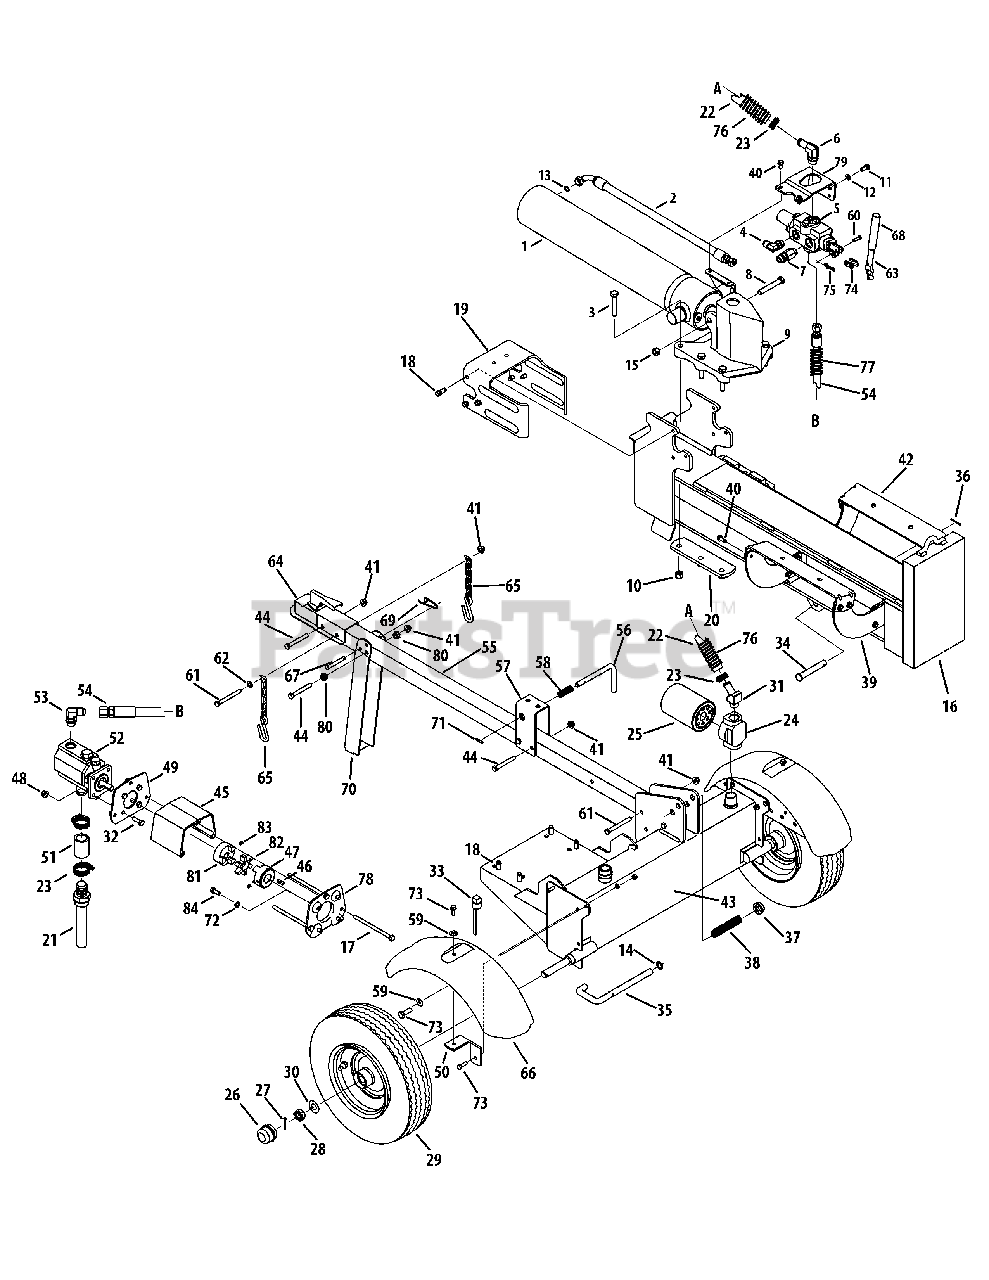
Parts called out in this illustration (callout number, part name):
1	Hydraulic Cylinder
2	Hydraulic Tube
3	Hex Cap Screw, 1/2-20 x 2.75
4	90 Degree Solid Adapter
5	Control Valve
6	Return Elbow
7	Nipple Pipe, 1/2-14
8	Hex Cap Screw, 1/2-13 x 3.25
9	Wedge Assembly
10	Hex Lock Nut, 1/2-20
11	Hex Cap Screw, 3/8-16 x .75
12	Lock Washer, 3/8
13	O-Ring, .489 ID x .070 Dia.
14	Flat Washer, .635 x.93 x.06
15	Hex Lock Nut, 1/2-13
16	Beam Assembly
17	Hex Screw, 5/16-18 x 4.00
18	Self Tapping Screw, 3/8-16 x 1.0
19	Dislodger Bracket
21	Inlet Filter
22	Return Hose, 3/4 x 44
23	Hose Clamp, 5/8
24	Filter Housing
25	Oil Filter
27	Cotter Pin
28	Slotted Nut, 3/4-16
29	Complete Wheel Assembly
29	Dust Seal
29	Roller Bearing
30	Flat Washer, .760 x.500
31	Hydraulic Fitting, 1 1/16 Orb x .75
32	Hex Screw, 5/16-18 x 1.00
33	Vented Dipstick
34	Clevis Pin
36	Cotter Pin
38	Compression Spring
39	Log Tray Bracket
40	Hex Washer Screw, 5/16-18 x .750
41	Flange Lock Nut, 3/8-16
43	Frame Assembly
44	Hex Bolt, 3/8-16 x 3
45	Coupling Shield
46	Square Key, 3/16" x .75
47	Coupling, .750
48	Flange Lock Nut, 5/16-18
49	Rear Coupling Support Bracket
50	Fender Mounting Bracket
53	45 Degree Elbow Fitting
54	High Pressure Hydraulic Hose
55	Tongue Assembly
56	Latch Rod
58	Compression Spring
59	Flat Washer
60	Clevis Pin
61	Hex Cap Screw, 3/8-16 x 3.50
62	Flat Washer, .375 x.738 x.063
63	Hydraulic Valve Control
64	Hitch Coupling Assembly
67	Clevis Pin
69	Spring Pin
71	Spiral Pin
72	Lock Washer, 5/16
73	Self-Tapping Screw, 5/16-18 x 1.00
74	Valve Handle Link
75	Cotter Pin, Bow Tie
76	Hose Guard, 44"
77	Hose Guard, 48"
78	Front Coupling Support Bracket
79	Outer Valve Bracket
80	Plastic Bushing, .380 ID
81	Coupling, .500
82	Spider Bushing
83	Set Screws
84	Hex Cap Screw, 5/16-24 x .75
